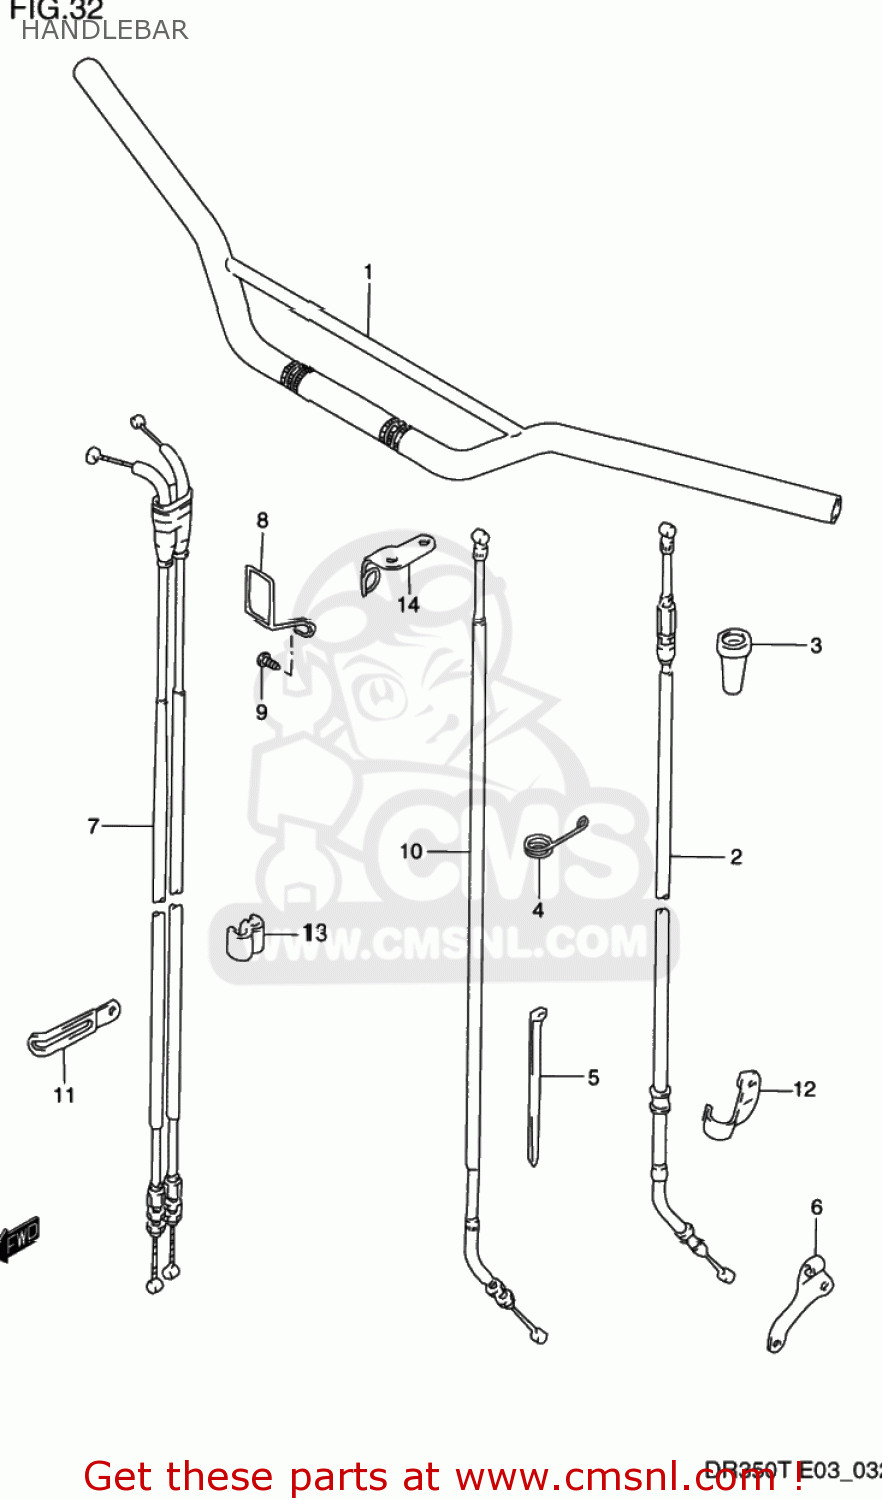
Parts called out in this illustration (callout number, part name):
1	HANDLEBAR
2	CABLE ASSEMBLY,CLUTCH
3	BOOT,CLUTCH CABLE
4	GUIDE,CLUTCH CABLE
5	CLAMP(L:145)
6	STOPPER,CLUTCH CABLE
7	CABLE SET,THROTTLE
8	GUIDE,CABLE
9	BOLT
10	CABLE ASSY,DECOMP
11	CLAMP
12	CLAMP,CLUTCH CABLE
13	CLIP
14	GUIDE,CABLE
